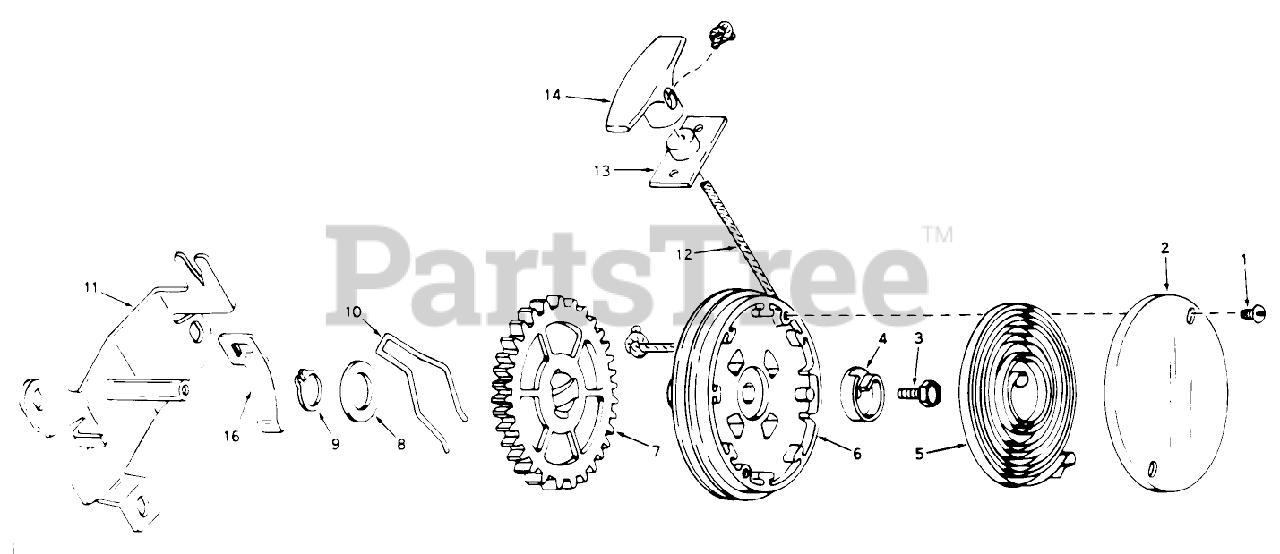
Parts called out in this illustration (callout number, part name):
1	Screw, Cover
2	Cover, Spring
4	Hub Spring
5	Spring, Rewind
6	Pulley
7	Gear
8	Washer
9	Ring, Snap
11	Bracket Assy. Mounting
12	Rope, Starter
13	Bracket Assy.
14	Handle-Starter
16	Clip Rope
